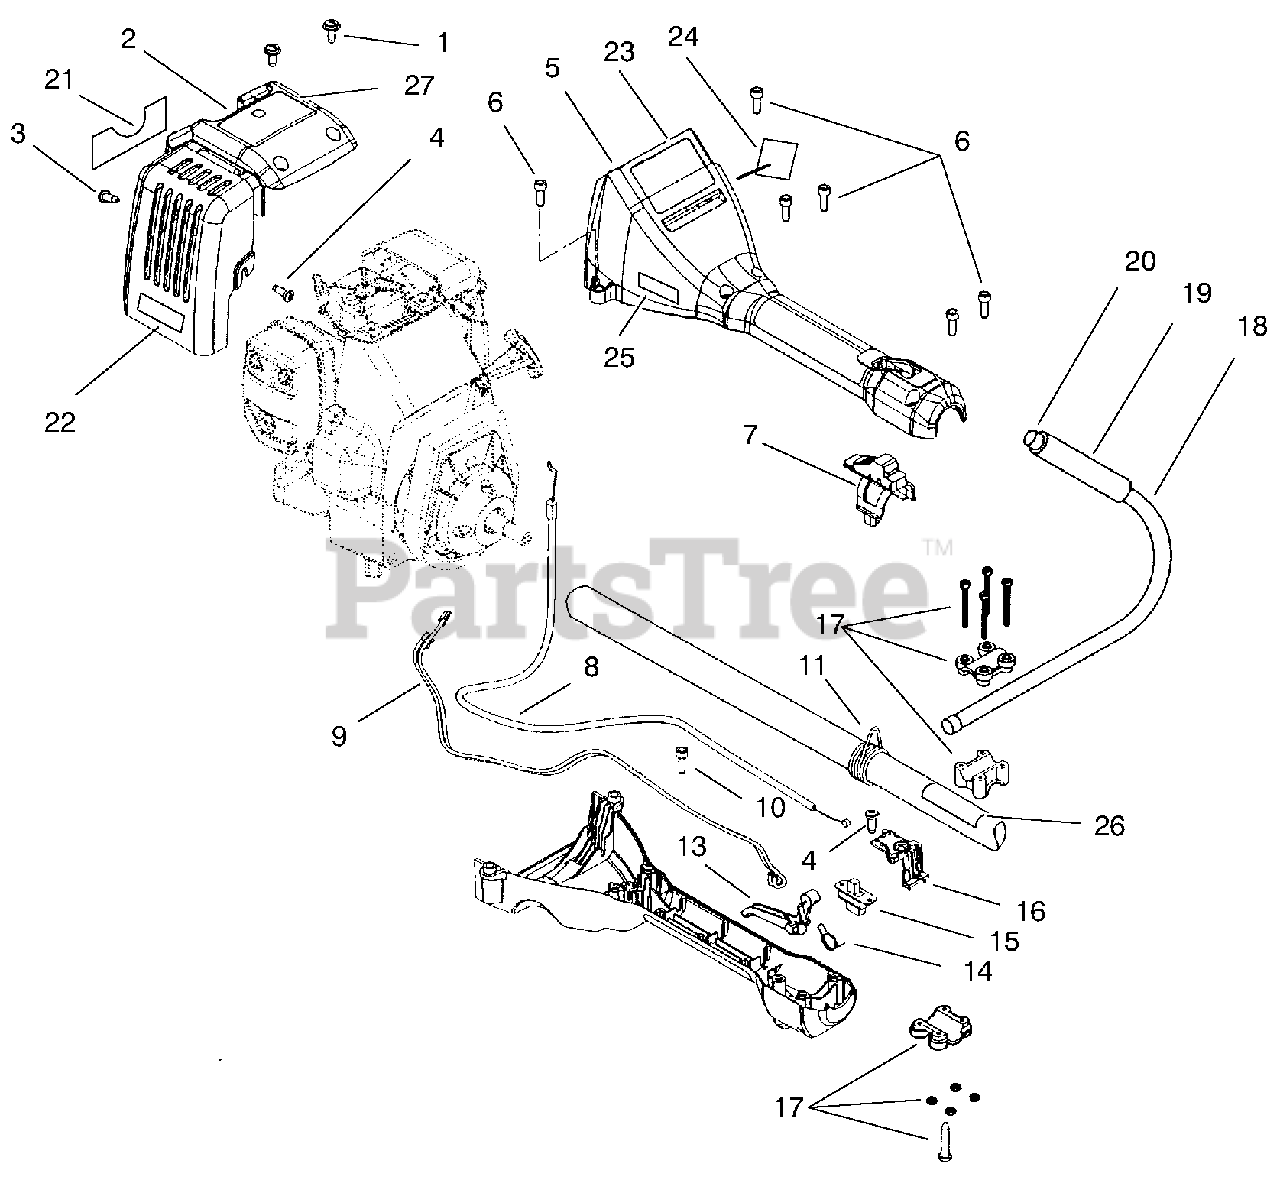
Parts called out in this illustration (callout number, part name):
2	Cover-Engine
4	Screw-Engine Cover
5	Handle Assembly
7	Slide-Switch
8	Cable-Throttle
9	Lead-Wire 18"
10	Screw-Anti-Rotation
11	Clip-Shoulder Strap
13	Trigger
16	Retainer-Switch & Trigger
17	Handle Bracket Assembly
18	J-Handle Assembly (Incl. Ref. # 19 & 20)
20	Tube Closure
21	Decal-Oil
22	Decal-Hot Surface
23	Decal-Toro
24	Decal-Carburetor
25	Decal-Unleaded Gas
26	Decal-Safety Symbols
27	Decal-Trimmer
